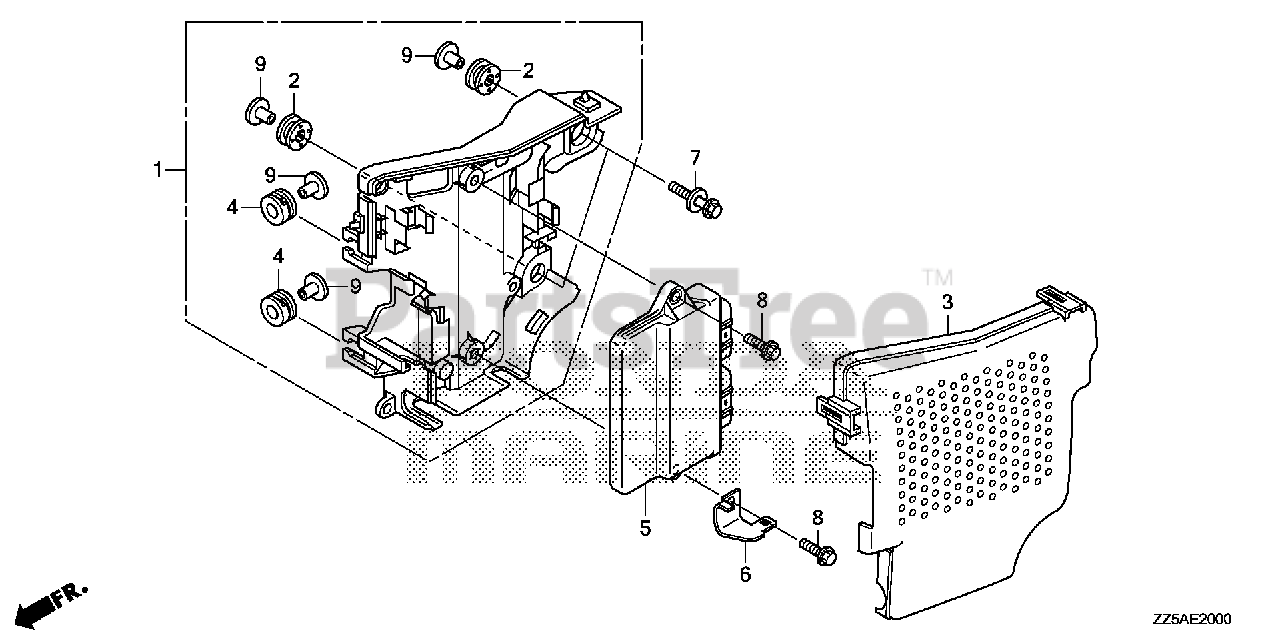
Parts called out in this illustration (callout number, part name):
1	CASE ASSY., ELECTRONIC PARTS
2	GROMMET, ELECTRONIC PARTS CASE
3	COVER, ELECTRONIC PARTS
4	GROMMET, MODULE IGNITION CONTROL CASE (CDI)(B)
5	CONTROL UNIT, ELECTRONIC
6	BRACKET, ELECTRONIC CONTROL UNIT
7	BOLT-WASHER (6X27) (CT200)
8	BOLT, FLANGE (6X20)
9	COLLAR, MODULE IGNITION CONTROL CASE (CDI)
